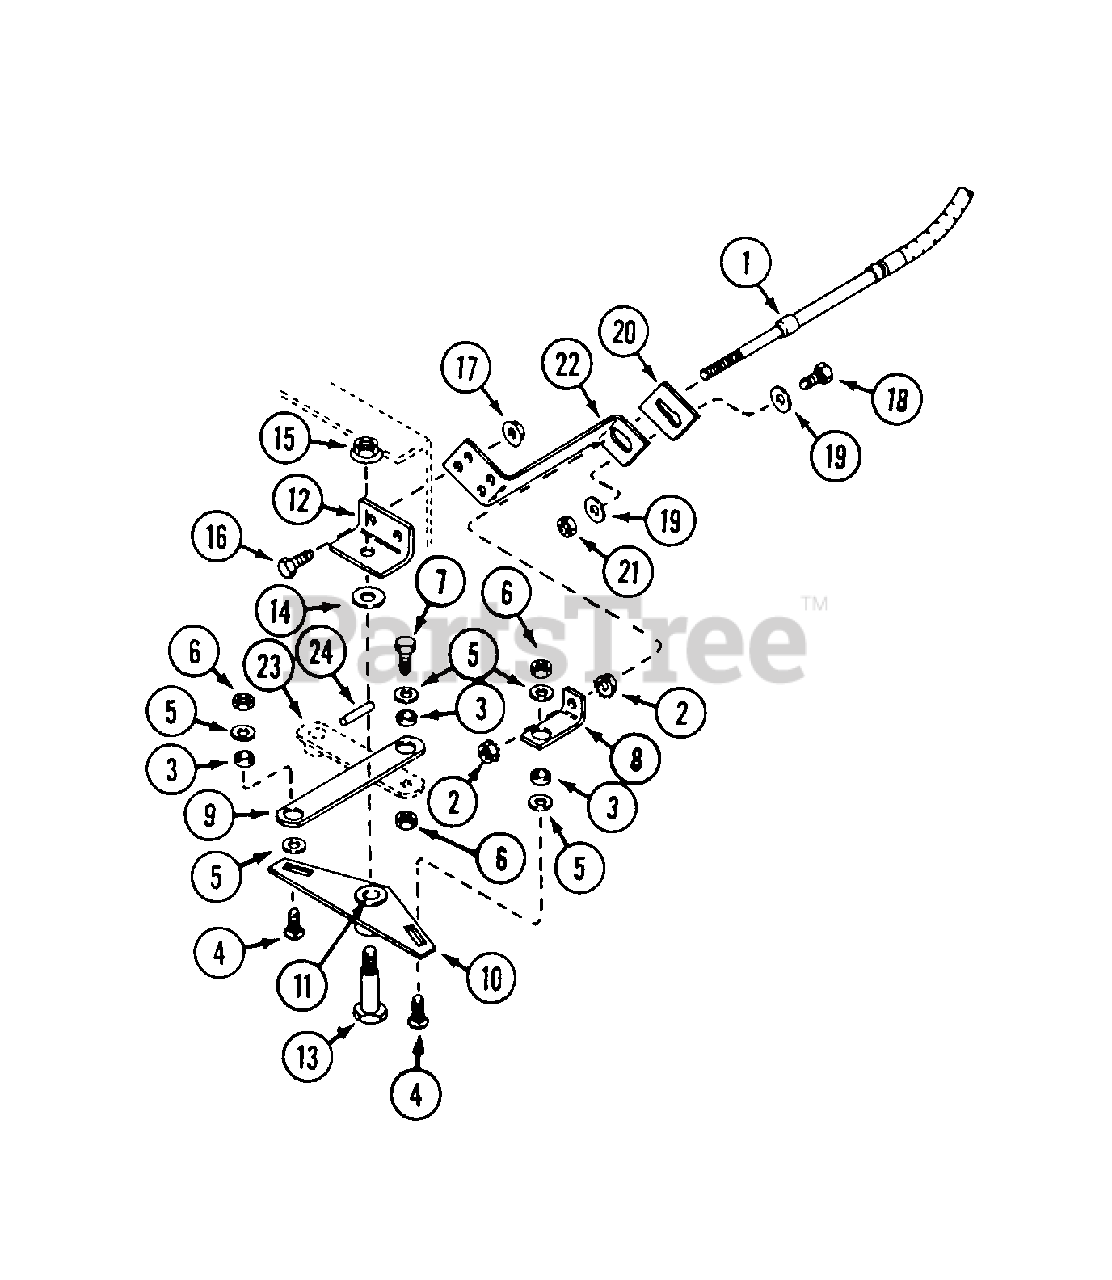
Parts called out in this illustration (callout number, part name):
1	CABLE - steering 46"
2	NUT - #10 - 32
3	BUSHING - steering cable
4	BOLT - 1/4" - 20 x 1" carriage
5	WASHER - 1/4"
6	NUT - 1/4" - 20
7	BOLT - 1/4" - 20 x 1"
8	BRACKET - steering cable end
9	LINK - control cable
12	BRACKET - bellcrank mounting
13	BOLT - shoulder
14	WASHER - 1/2"
15	NUT - 3/8" - 16 flange lock
16	BOLT - 5/16" - 18 x 1"
17	NUT - 5/16" - 18
18	BOLT - 1/4" - 20 x 1"
19	WASHER - 1/4"
20	PLATE - cable mounting
21	NUT - 1/4" - 20 lock
22	BRACKET - cable mounting
23	ARM - transmission
